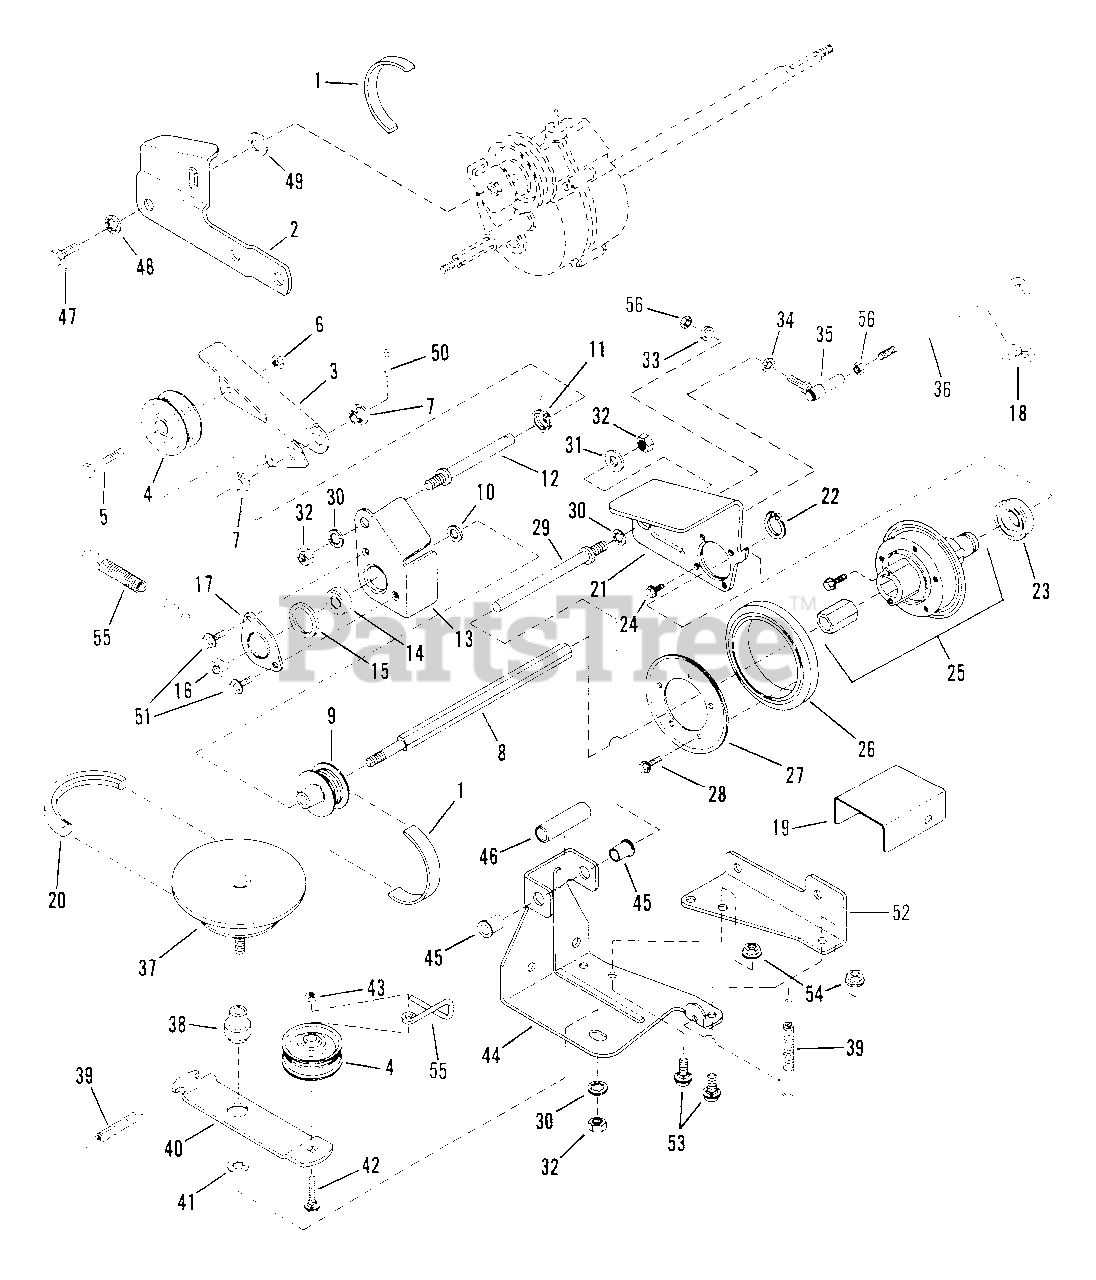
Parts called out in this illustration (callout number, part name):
1	BELT, Poly-Vee
2	LINK, Differential
3	ARM, Clutch Idler
4	PULLEY, Idler
5	SCREW, 1/4-28x1-3/8" Hex Head Cap
6	NUT, 1/4-28 Hex Lock
7	BUSHING, 3/8 I.D. Nylon
8	SHAFT, Hex
9	PULLEY, Poly-V
10	WASHER, 3/8" Flat
11	SPRING, Torsion
12	STUD
13	HOLDER, Bearing (Inner Half)
14	BEARING, Ball(.385" ID, 1" OD, .312" Thick)
15	O-RING
16	NUT, 3/8-24 Hex Center Lock
17	HOLDER, Bearing (Outer Half)
18	CLIP, 1/4 Right Arc (Transfer Rod)
19	SHIELD, Hex Shaft (European Models Only)
20	BELT, Engine Drive
21	PLATE, Thrust
22	RING, Retaining
23	BEARING, Ball
24	SCREW, #10-32x1/4" Self-Tapping Machine
25	ASSEMBLY, Hub
26	RING, Driven
27	PLATE, Ring Retaining
28	SCREW, #10-24 x 1/2" Hex Washer Self-Tap (Torx)
29	GUIDE, Thrust Plate
30	WASHER, 3/8 Internal Tooth Lock
31	WASHER, 3/8" Flat
32	NUT, 3/8-24 Hex
33	WASHER, 1/4 Flat
34	WASHER, 1/4 Internal Tooth Lock
35	JOINT, Ball
36	LINK, Transfer
37	ASSEMBLY, Drive Disc
38	BUSHING
39	SPRING (Wheel Drive & Idler)
40	ARM, Idler
41	RETAINER, 3/8 Bolt
42	BOLT, 1/4-20x1-1/2" Carriage
43	NUT, 1/4-20 Hex Center Lock
44	BRACKET, Deck
45	BUSHING, Flange
46	SPACER
47	SCREW, 5/16-18x1/2" Hex Head Cap
48	WASHER, 5/16 Internal Tooth Lock
49	WASHER, Spring
50	PIN, 3/32x1/2" Cotter
51	SCREW, 1/4-20x1/2" Self-Tapping
52	BRACKET, Strap
53	BOLT, 5/16-18 x 5/8" Short Neck Carriage
54	SPRING, Clutch
55	SCRAPER, Drive Pulley
56	NUT, 1/4-28 Hex
